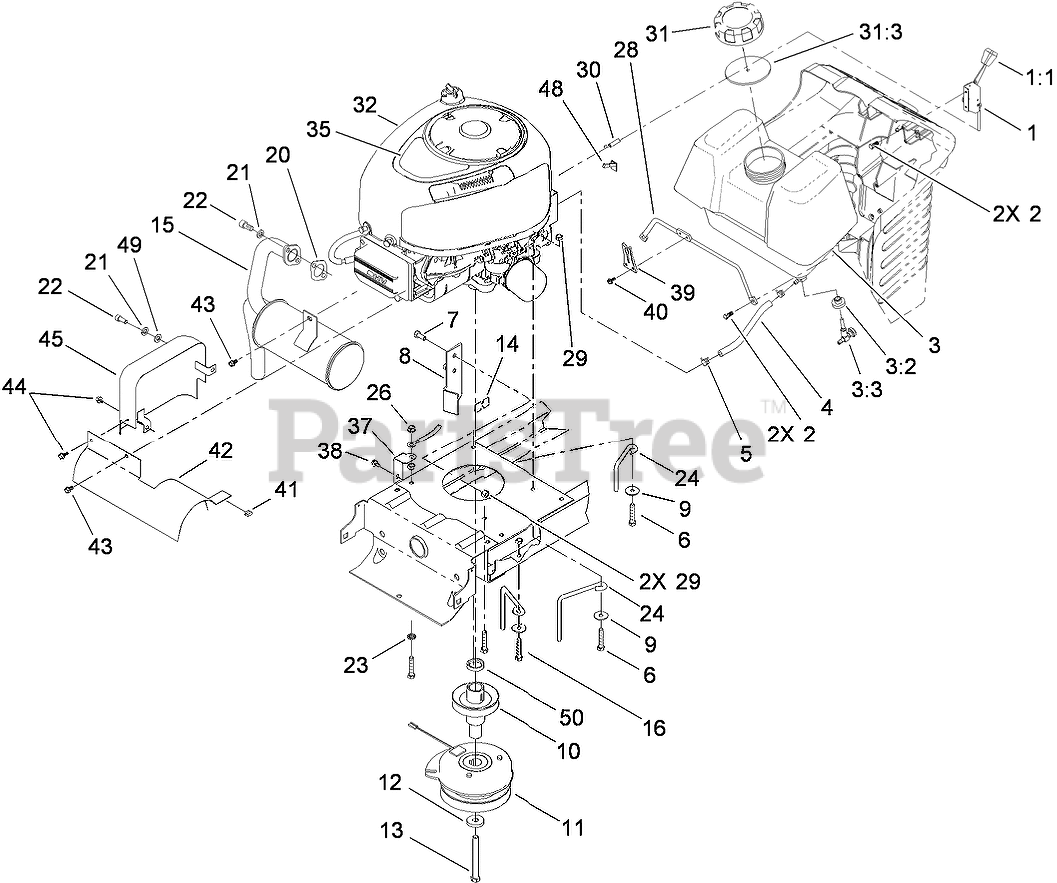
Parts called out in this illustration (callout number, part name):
1	THROTTLE CONTROL ASM
2	SCREW-SPECIAL
3	GAS TANK ASM
3:2	BUSHING
3:3	VALVE-FUEL
4	HOSE-FUEL
5	CLAMP-HOSE
6	SCREW-HH
7	SCREW-HH
8	STOP-CLUTCH
9	WASHER-PIVOT
10	PULLEY-ENGINE
11	CLUTCH-PTO, ELECTRIC
12	WASHER
13	SCREW-HH
14	BUMPER
15	MUFFLER-EXHAUST
16	SCREW-HWH, TAPTITE
20	GASKET-EXHAUST
21	WASHER-LOCK
22	SCREW-HSH
23	WASHER-LOCK
24	GUIDE-BELT, RH
26	NUT-KEPS
28	ROD-TANK, GAS
29	NUT-LOCK, NI
30	THROTTLE CABLE ASM
31	GAS CAP ASM
31:3	GASKET-CAP, GAS
35	DECAL-ENGINE
37	BRACKET-GROUND
38	SCREW-HWH
39	LATCH-HOOD
40	SCREW-HWH
41	CLIP-TINNERMAN
42	EXHAUST SHIELD ASM
43	SCREW-HWH
44	SCREW-HWHTF
45	HEAT SHIELD ASM
48	REDUCER-THROTTLE, RPM
49	WASHER-PLAIN
50	SPACER
